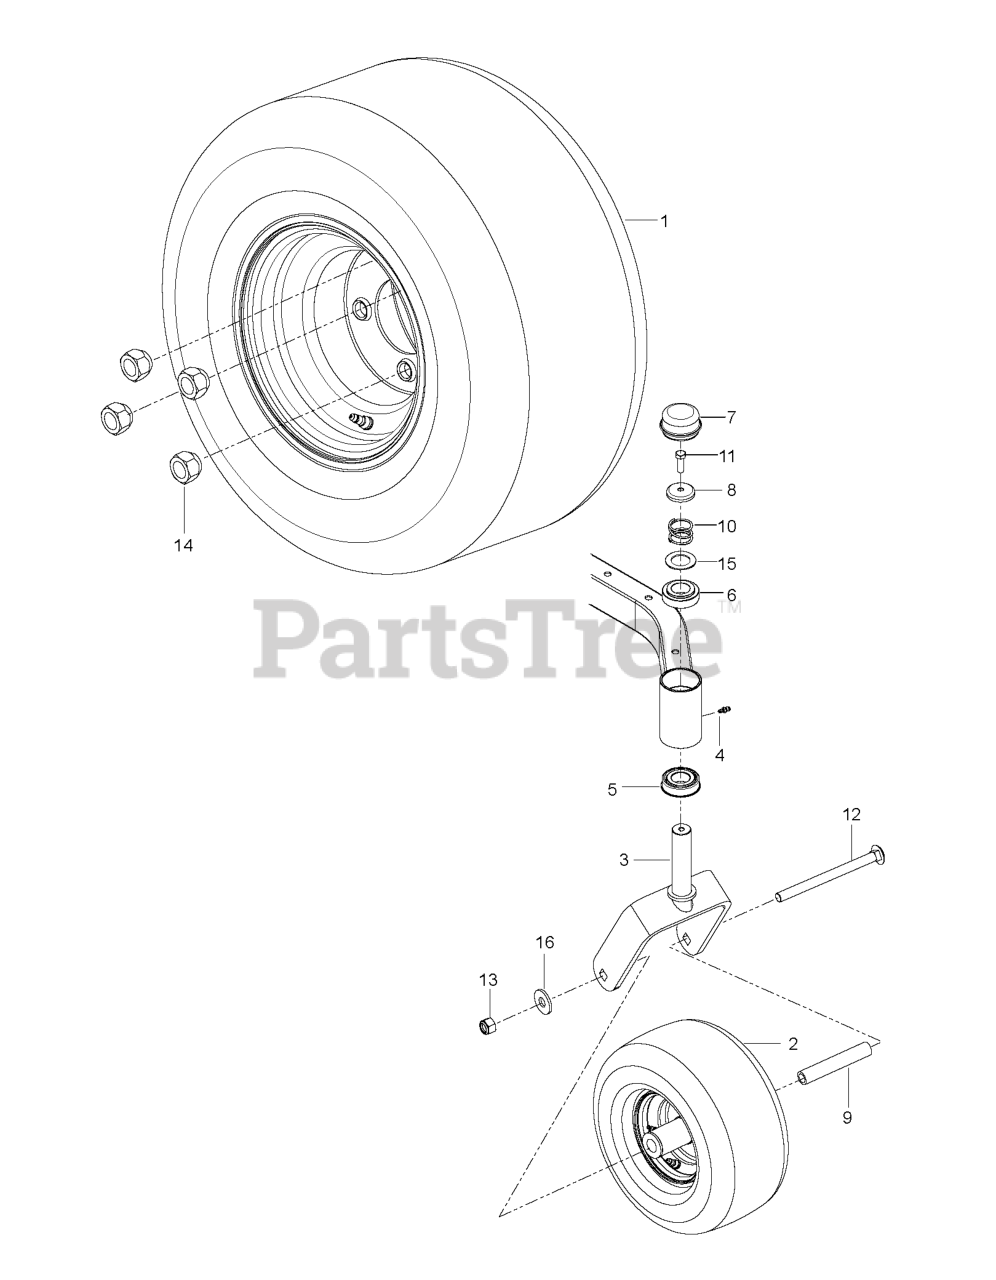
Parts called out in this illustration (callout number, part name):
1	WHEEL.18X8.50-8.4P.K500.8X7.4H
2	WHEEL.ASSY.FRONT.CASTER.11X6-5
3	YOKE CASTER ASM SNAPPER RED X6
4	ZERK, 3/16, DRIVE IN
5	BEARING FLANGED
6	BUSHING, CASTER
7	GREASE CAP
8	CASTER.PLUG
9	SPACER.PIVOT
10	SPRING, CASTER
11	5/16-18X1 HHB G5W/NY
12	RHSNB 1/2-13 X 7.5
13	NUT. 1/2-13 HEX CNTRLK GR 5 ZD
14	LUG NUT 1/2F
15	WASHER, 1.025 ID X 1.64
16	WASHER.9/16 X 1 3/8 X 12 GA.
